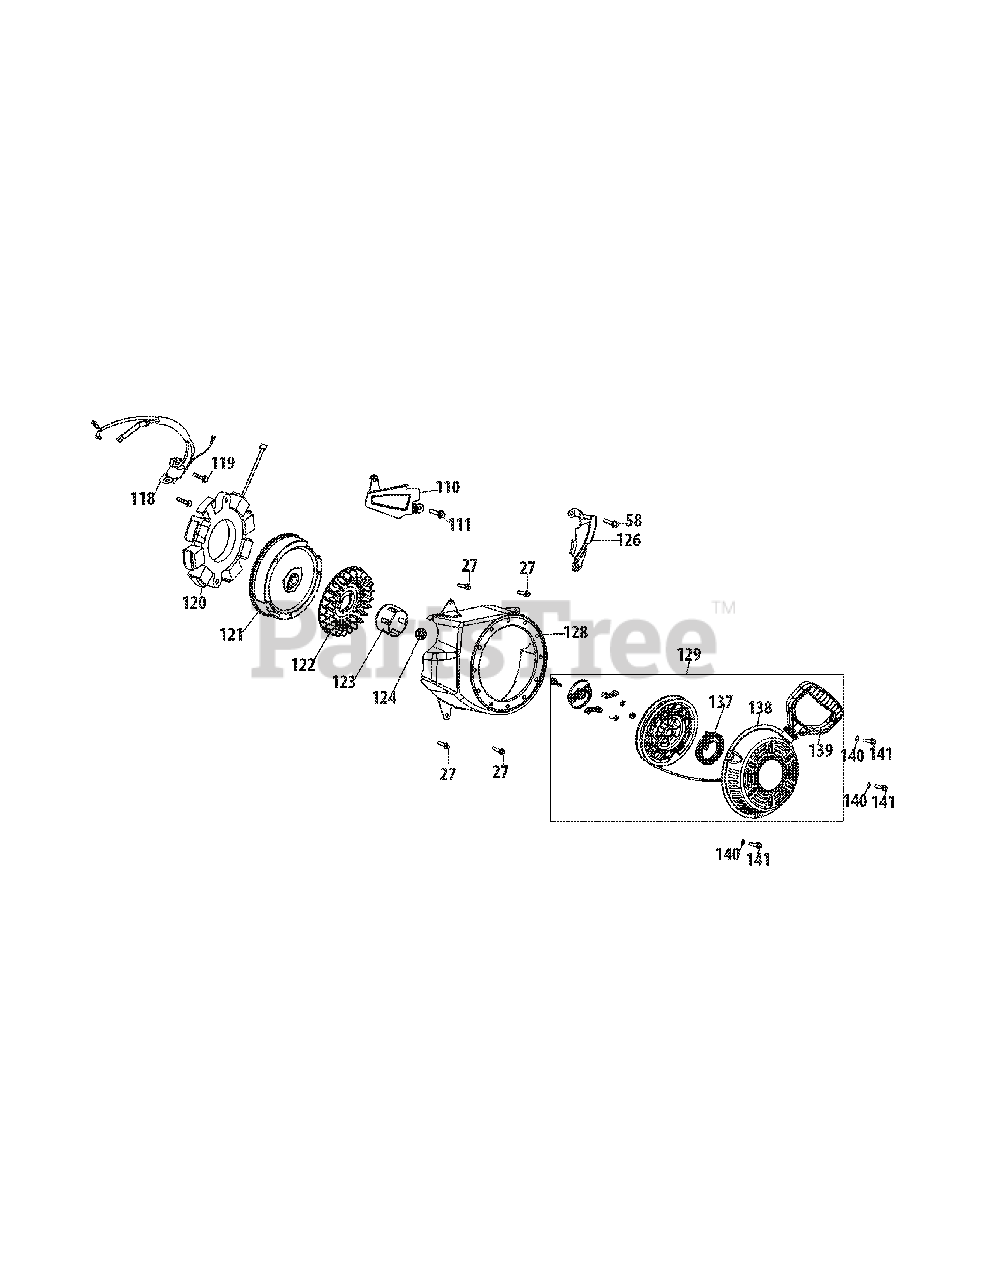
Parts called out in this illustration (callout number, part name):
27	Bolt, M6×12
58	Bolt, M6×12
110	Choke Plate
111	Bolt, M6×10
118	Ignition Module
119	Bolt, M6×25
120	Charging Coil
121	Flywheel
122	Cooling Fan
123	Starter Cup
124	Flange Nut M14×1.5
126	Lower Shield
128	Blower Housing
129	Recoil Starter
137	Recoil Spring
138	Starter Cover
139	Starter Handle
140	Washer, 6
141	Bolt M6×10
